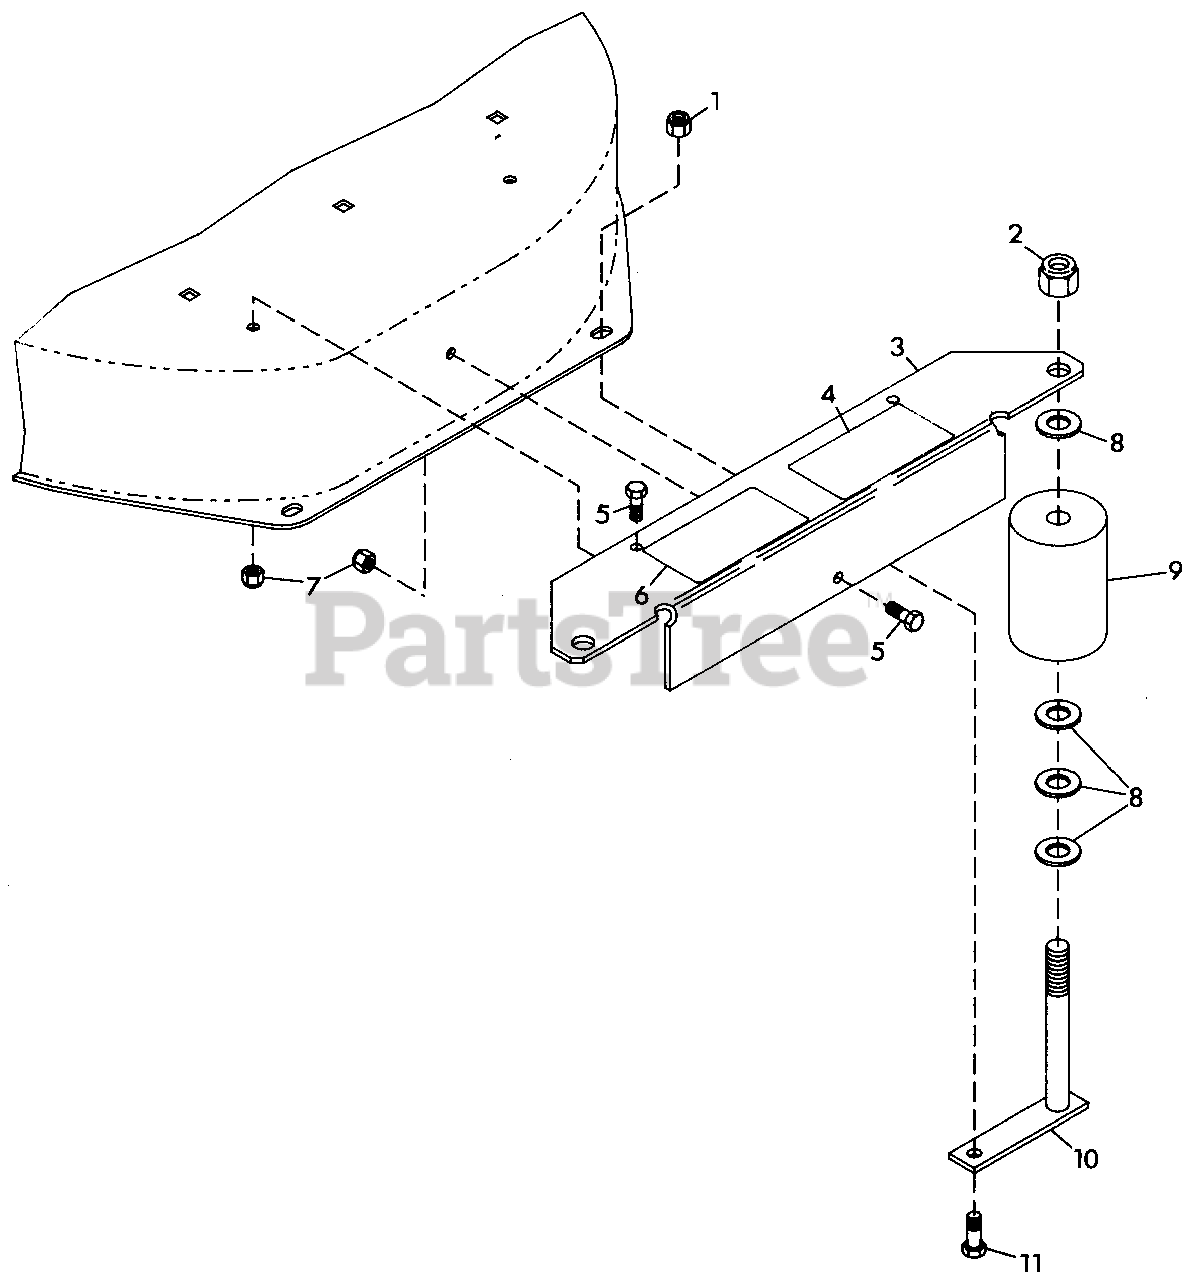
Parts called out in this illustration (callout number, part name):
1	NUT, LOCK 3/8-16
2	NUT, LOCK 5/8-11
3	BRACKET
4	DECAL, WARNING EYE
5	BOLT, HEX 5/16-18X.87
6	DECAL, DANGER HAND
7	NUT, LOCK 5/16-18
8	WASHER, FLAT .656X1.250X.10
9	ROLLER, GAGE
10	WELDMENT, ROLLER BRACKET
11	BOLT, HEX 3/8-16X1.00
